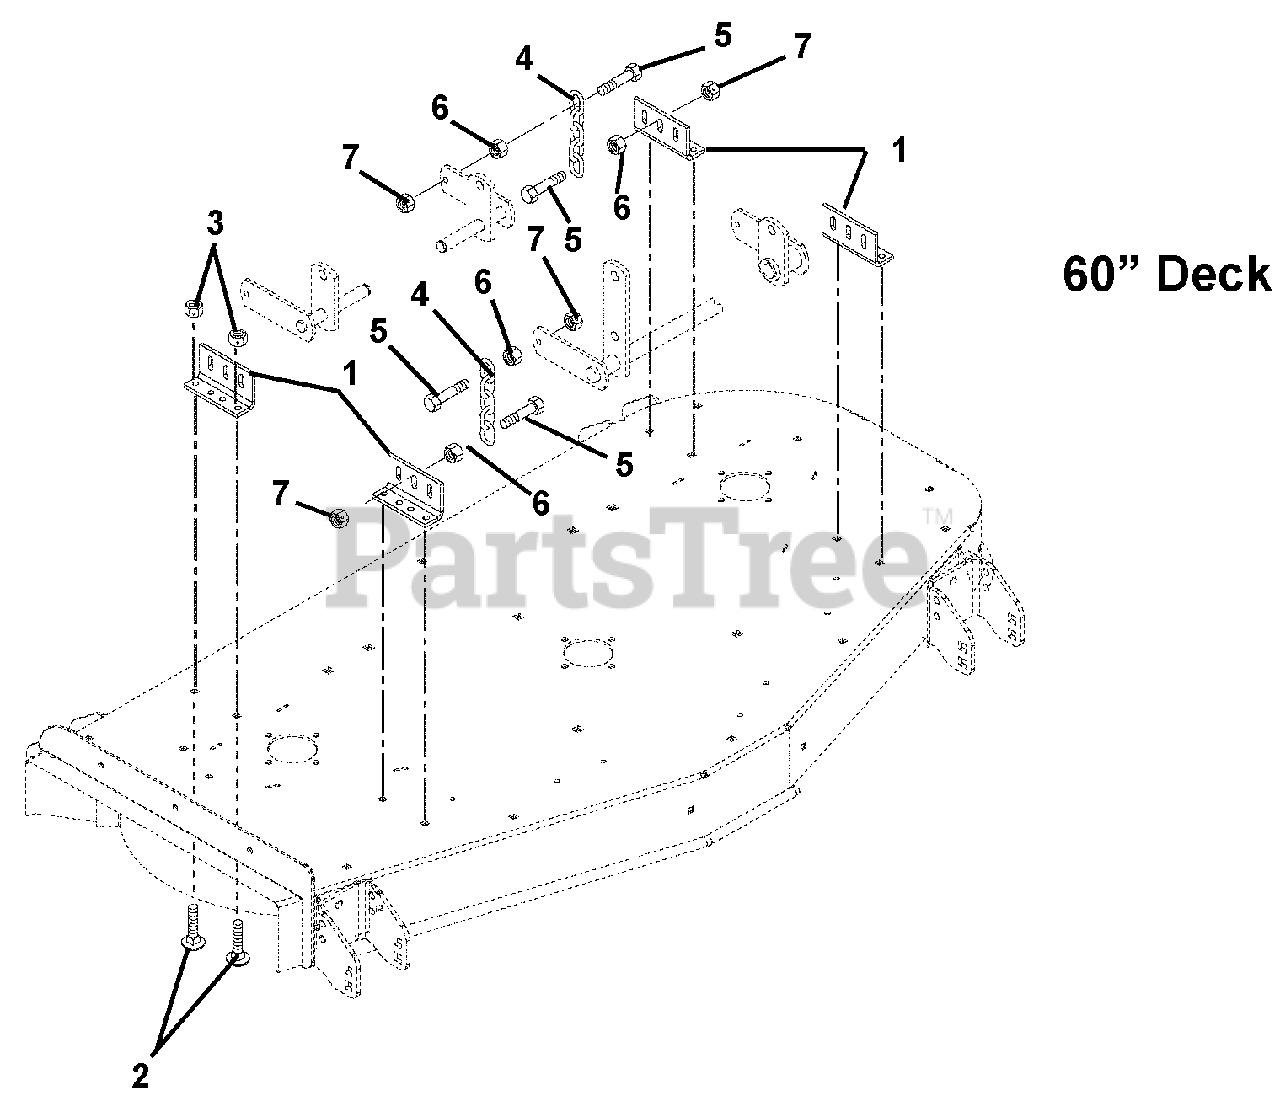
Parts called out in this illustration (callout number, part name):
1	Bracket, Mower Mounting
2	Bolt-Round Head Square Neck .38-16 x 1.00 Grade 2
3	Nut-Locking-Top-Flange .38-16
4	Chain, Link
5	Bolt-Hex M12-1.75 Grade 5
6	Nut, Spin Lock Flange M12-1.75
7	Nut-Locking-Top-Flange M12-1.75
